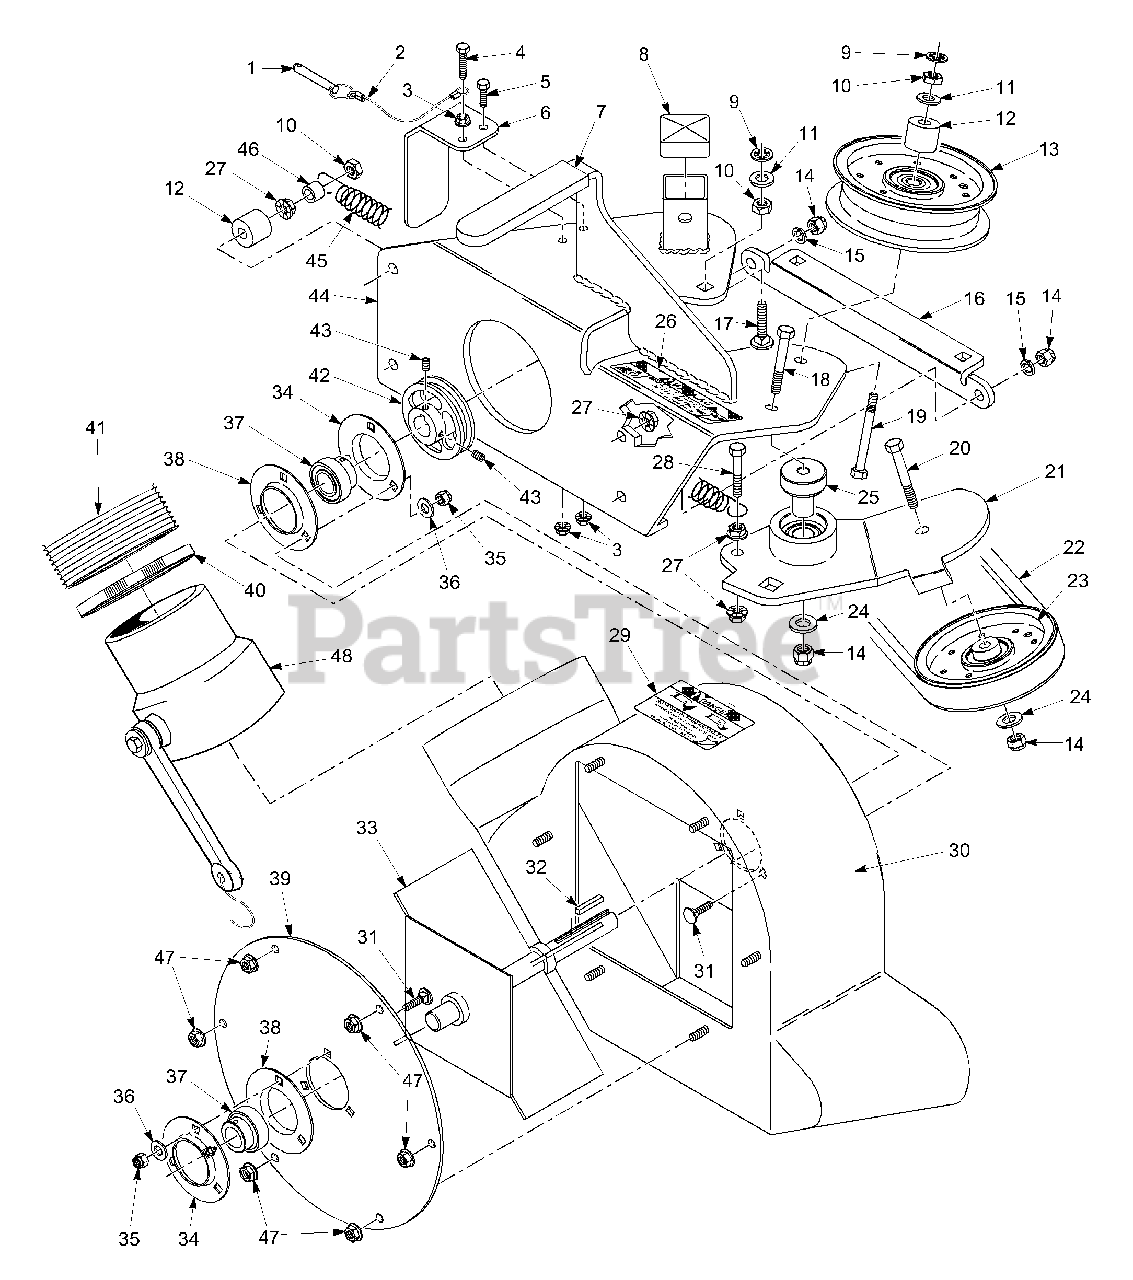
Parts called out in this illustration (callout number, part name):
1	Pin, Ring 2-1/4" Long
2	Lanyard, Deck Height Pin
3	Nut, Serr. Flange 1/4-20
4	Bolt, Hex Head 1/4-20 x 1-1/4"
5	Bolt, Hex Head 1/4-20 x 3/4"
6	Belt Cover, Rear
7	Grip, Blower Lever
8	Cap, Square
9	Nut, Push On 3/8 Thread
10	Lock Nut, 3/8-16
11	Flatwasher, 3/8-.391 x .938 x .105
12	Spacer
13	Pulley, Idler 3" Dia. - 52" Cutter Deck
14	Nut, Elastic Stop 3/8-16
15	Lockwasher, 3/8-16
16	Plate, Catch Mounting
17	Bolt, Carr. 3/8-16 x 1-1/2"
18	Bolt, Hex Head 3/8-16 x 3" - 52"
19	Bolt, Hex Head 3/8-16 x 3-1/2"
20	Bolt, Hex Head 3/8-16 x 1-3/4"
21	Idler Arm Assembly, GC-STT 52"
22	Belt, GC-STT 52"
23	Pulley, 3" O.D., GC-STT 52"
24	Washer, 3/8 Hardened
25	Pivot, Idler - 52"
26	Decal, Belt Cover
27	Nut, Serr. Flange 3/8-16
28	Bolt, Hex Head 3/8-16 x 1-1/2 Gr. 8
29	Decal, Danger
30	Blower Housing Assembly
31	Bolt, Carr. 5/16-18 x 3/4" Gr. 5
32	Key, 1/4 x 1/4 x 1-1/2"
33	Fan Weldment
34	Bearing Assembly
35	Nut, Elastic Stop 5/16-18
36	Flatwasher, 5/16-.344 x .688 x .065
37	Bearing w/Locking Collar
38	Bearing Flangette
39	Cover, Blower Housing
40	Clamp, 8-5/8" Max Dia.
41	Hose, 8.00" Dia. x 56.00" Long
42	Pulley, 4-3/4" O.D. - 1" Bore
43	Set Screw, 5/16-18 x 3/8"
44	Frame, Blower Mount - 52"
45	Spring, Main Drive
46	Spacer
47	Nut, Serr. Flange 5/16-18
48	Adapter w/Strap
